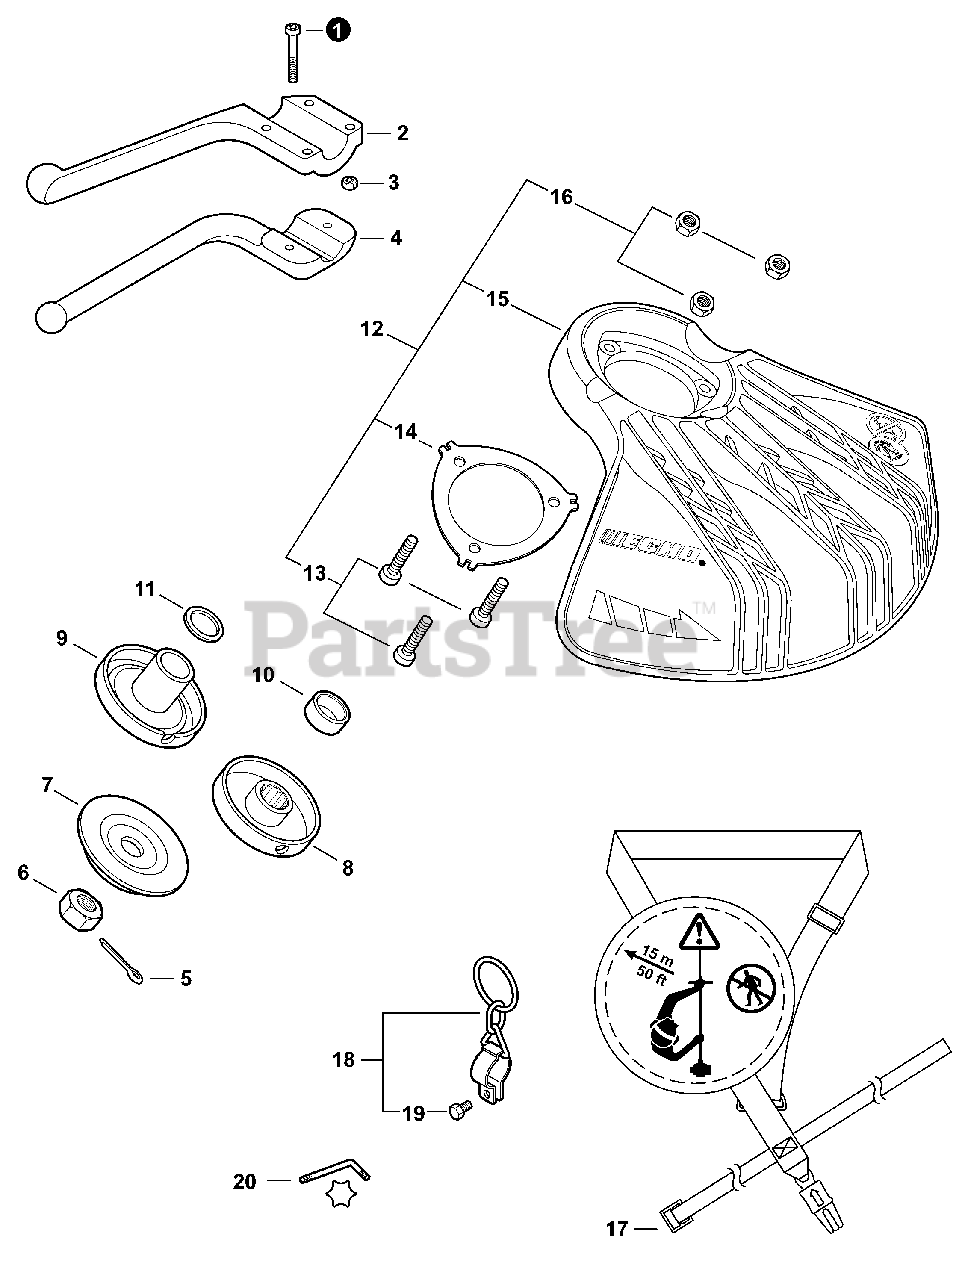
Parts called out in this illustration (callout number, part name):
1	BOLT, TORX 5×35
2	BAR, BARRIER
3	NUT M5
4	BAR, BARRIER
5	PIN, COTTER 2×22
7	PLATE, ADAPTOR - LOWER
8	PLATE, ADAPTOR - UPPER
9	PLATE, ADAPTOR - UPPER
10	SPACER 11.8×15×9
12	DEBRIS SHIELD KIT - BLADE
13	BOLT, TORX 5×25
14	PLATE, SHIELD
15	SHIELD, DEBRIS - BLADE
16	NUT, LOCK M5
17	HARNESS, SHOULDER
18	HANGER SET, HARNESS
19	BOLT, TORX 5×12
20	WRENCH, T27 80×30
